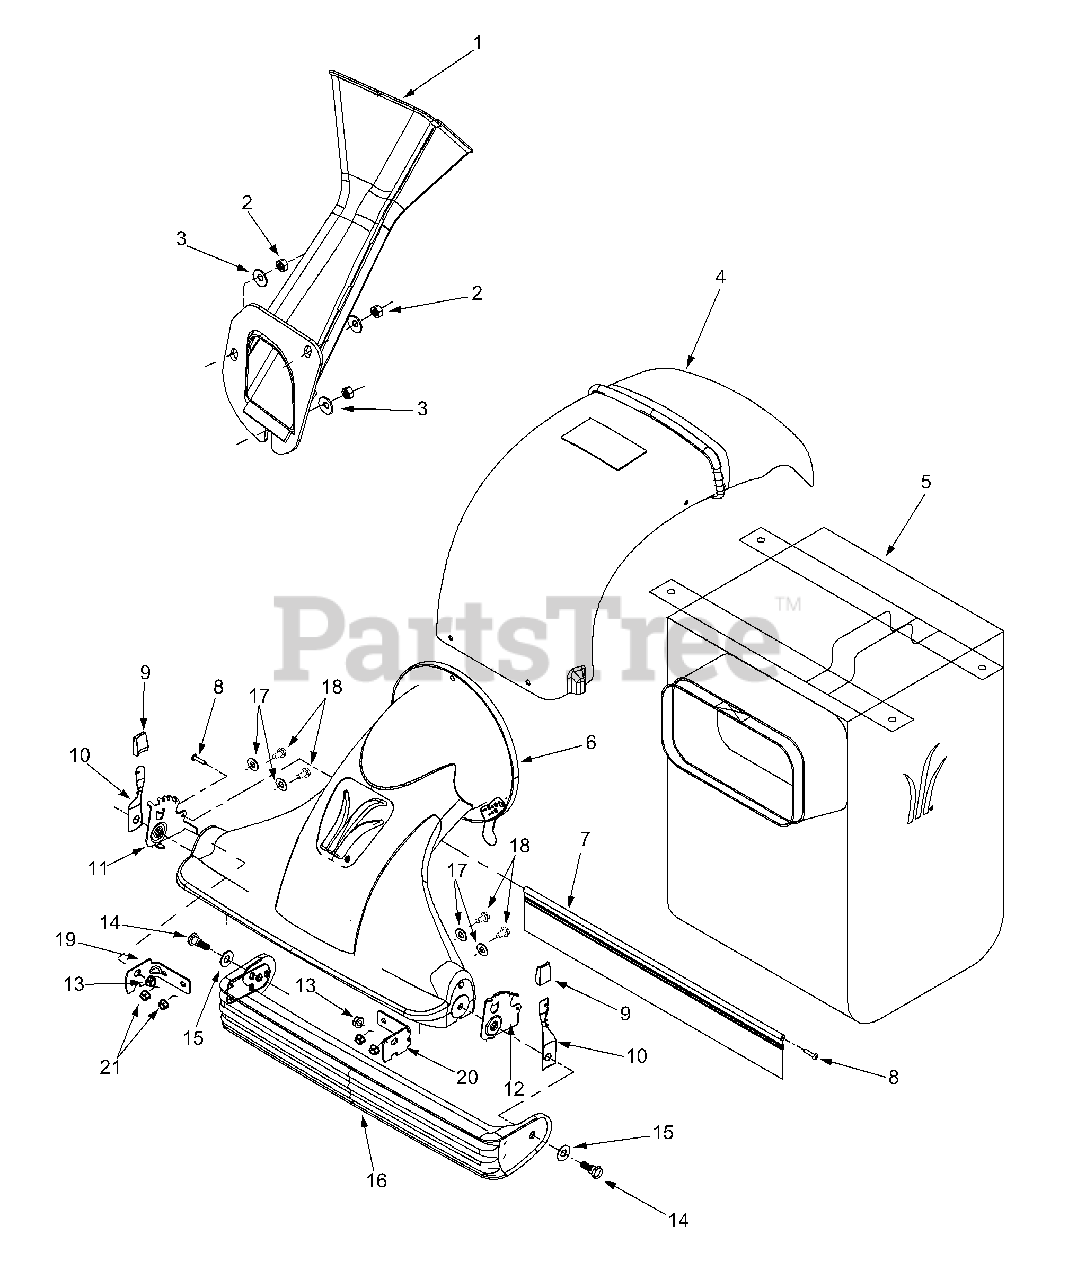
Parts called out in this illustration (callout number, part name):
2	Hex Nut 5/16-18
3	Bell Washer .340 ID x .872 OD
4	Discharge Chute
5	Bag
6	Nozzle Asm
7	Nozzle Flap
8	Screw
9	Height Adjustment Knob
10	Spring Lever
13	Hex Flange Lock Nut 3/8-16
14	Shoulder Screw
15	Flat Washer .510 x 1.12 x .060
16	Door Asm
17	Flat Washer .28 ID x .74 OD
18	Hex Cap Screw 1/4-20 x .625
